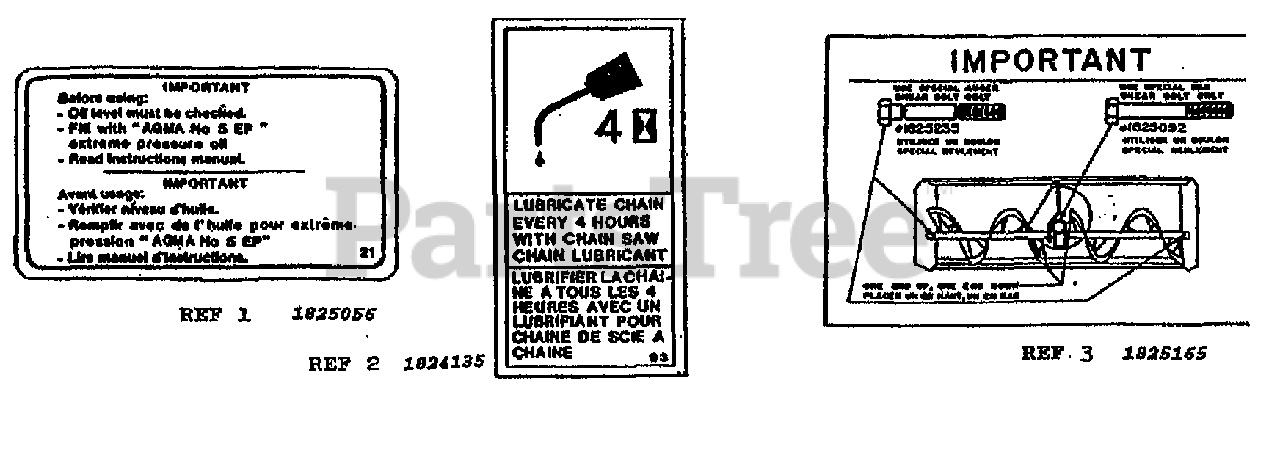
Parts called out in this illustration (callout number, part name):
1	DECAL-MAINTENANCE
2	DECAL-CHAIN LUB
3	DECAL-OPERATION
